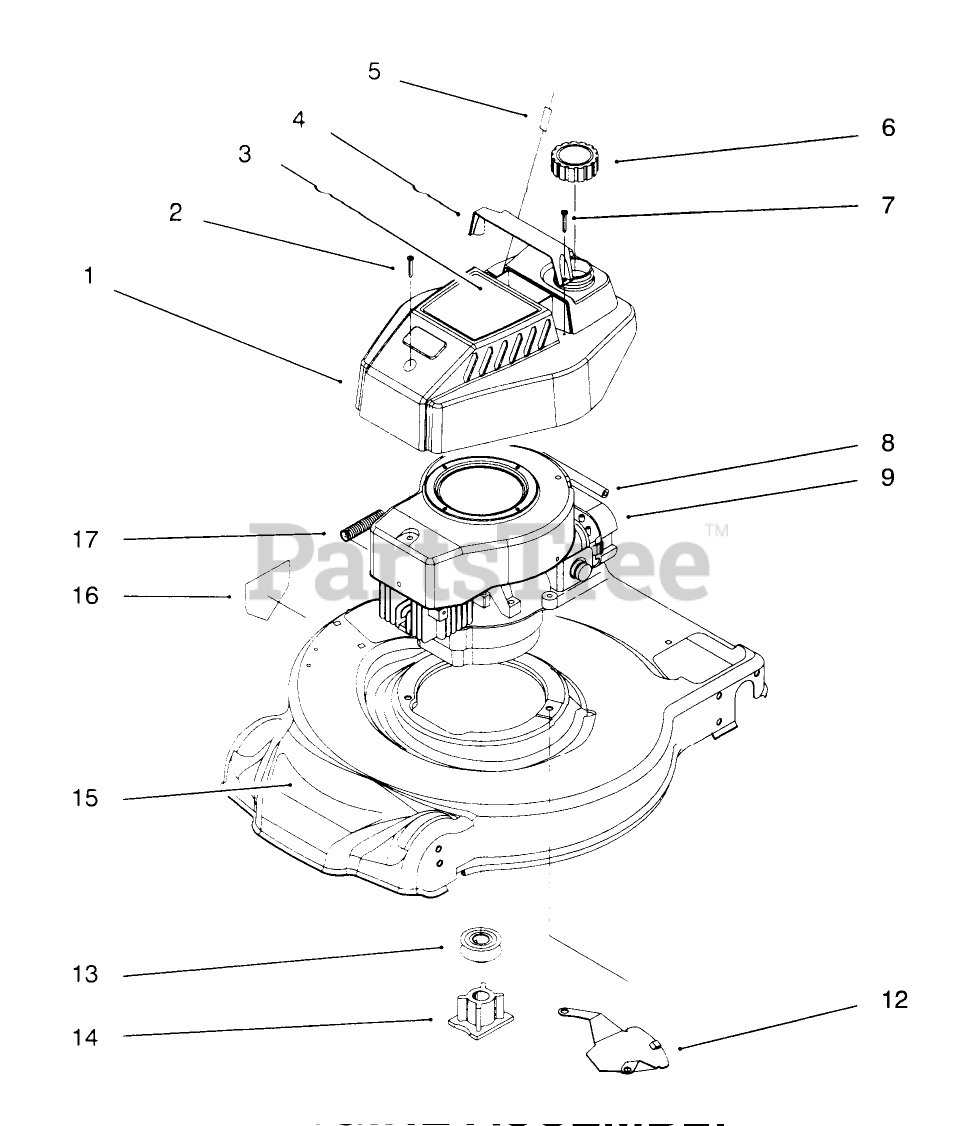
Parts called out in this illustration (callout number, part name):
1	TANK/SHROUD
2	SCREW
3	EXCEPT FOR SERVICE
4	STRAP - TANK
5	STOP-ROPE
6	GAS CAP ASSEMBLY
7	SCREW-PPH
8	HOSE-FUEL
9	Engine Assembly (Model No. 20442 Only)
13	PULLEY - DRIVER
14	BLADE RETAINER
16	DECAL-DANGER
17	SPRING-COMPRESSION
